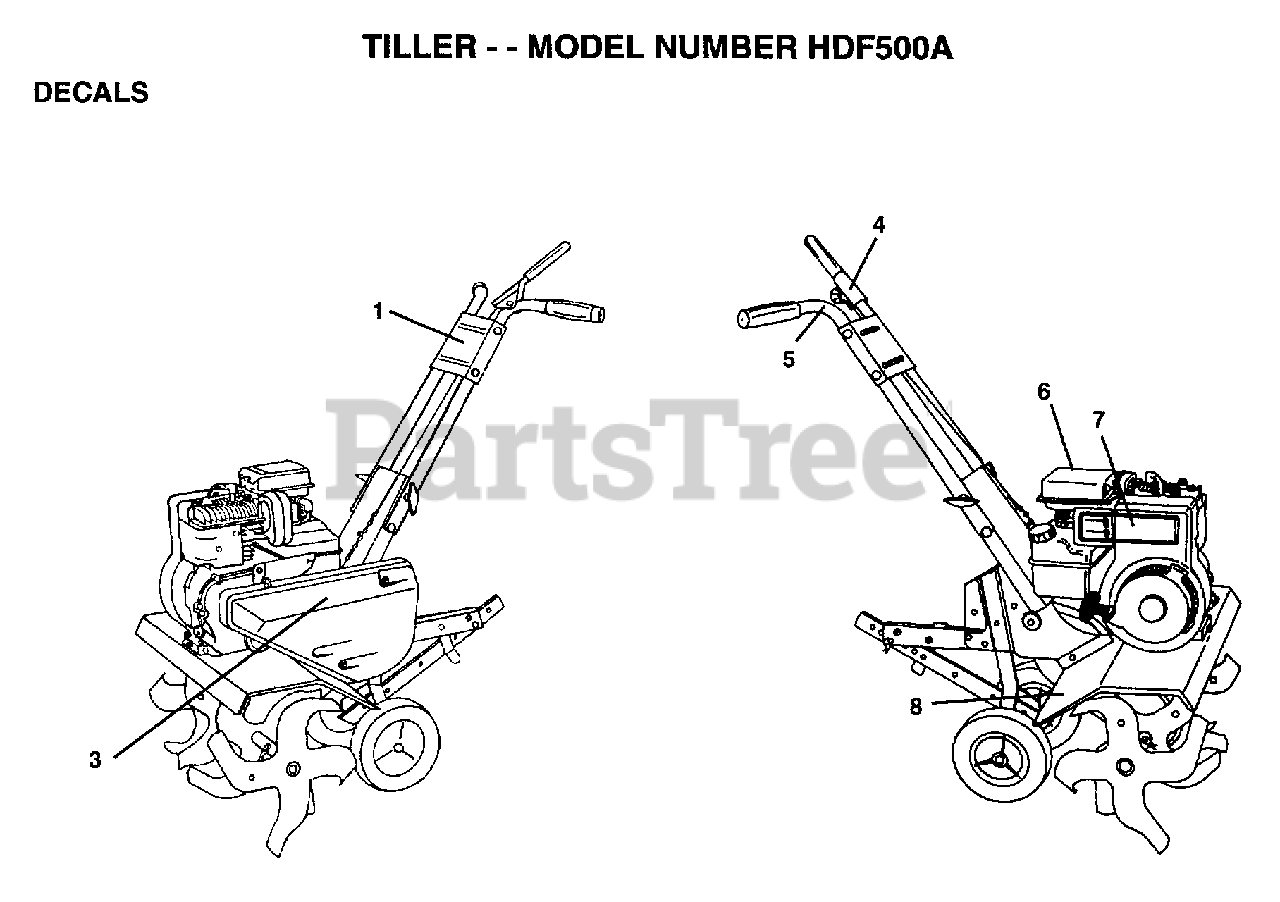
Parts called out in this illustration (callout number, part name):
1	DECAL.PNL.CNTRL.U
3	DECAL.GUARD.WEED.
4	DECAL.CONTROL
5	DECAL.HAND.PLACE
6	DECAL.CAUTION.E/S
7	DECAL, BRIGGS & STRATTON
8	DECAL.WARN.ROT.TI
